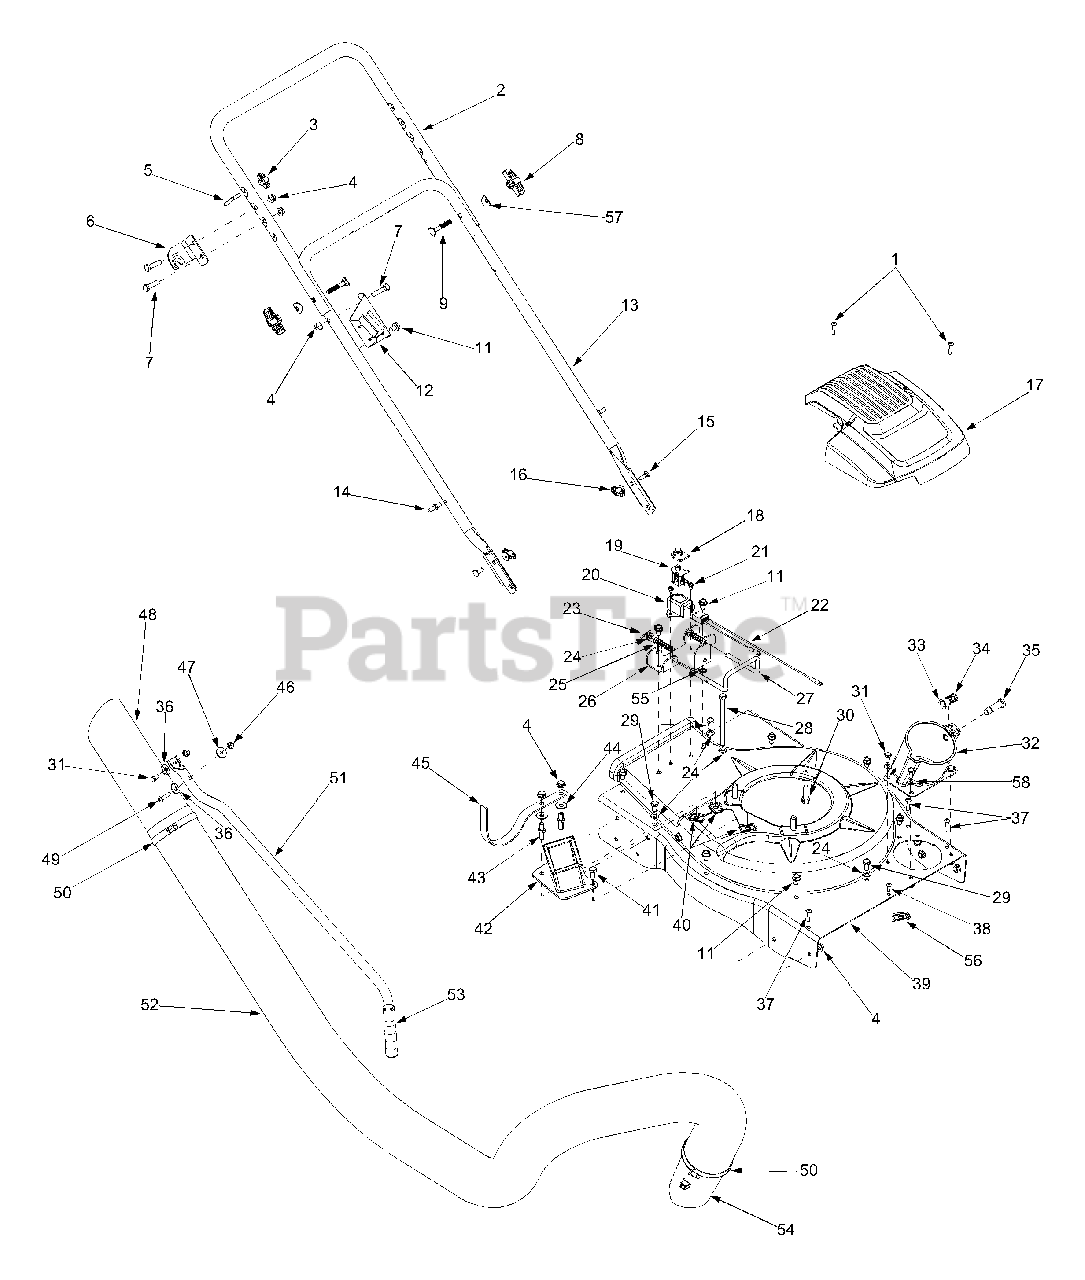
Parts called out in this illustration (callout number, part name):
1	Shoulder Screw #10 x.457
4	Flange Lock Nut 5/16-18
5	Eye Bolt
7	Hex Cap Screw 5/16-18 x 1.25
8	Handle Knob 5/16-18
9	Carriage Bolt
11	Hex Washer Screw 5/16-18 x.625
12	Lower Handle Bracket
14	Studs
15	Carriage Screw 1/4-20 x.75
16	Wing Nut 1/4-20
17	Shroud
18	Switch Cover
19	Safety Switch
20	Safety Switch Cover
21	Hex Washer Screw #10-16 x.50
22	Wire Harness
23	Cotter Pin
24	Flat Washer.330 ID x.630 OD
25	Compression Spring
27	Lock Rod
28	Hex Cap Screw 5/16-18 x 4.5
29	Hex Cap Screw 5/16-18 x.625
30	Hex Washer Screw 3/8-16 x 1.25
31	Hex Cap Screw 1/4-20 x.620
32	Hose Base Adapter
33	E Ring.500 Dia
34	Compression Spring
35	Clevis Pin
36	Flat Washer.271 ID x.630 OD
37	Screw #12-16 x 1.0
38	Machine Screw #10 - 16 x.500
40	U-Clip Lock Nut 5/16-18
41	Hex Cap Screw 5/16-18 x.75
43	Stud 5/16-18 x.56
44	Flat Washer.343 ID x.880 OD
47	Spacer
48	Hose Nozzle
49	Hex Cap Screw 1/4-20 x 2.625
50	Adjustment Clamp
52	Vacuum Hose
53	Handle Grip
54	Hose Adapter
55	External L-Washer 5/16
56	Speed Nut
57	Saddle Washer
58	Flat Washer.28 x.74 x.063
